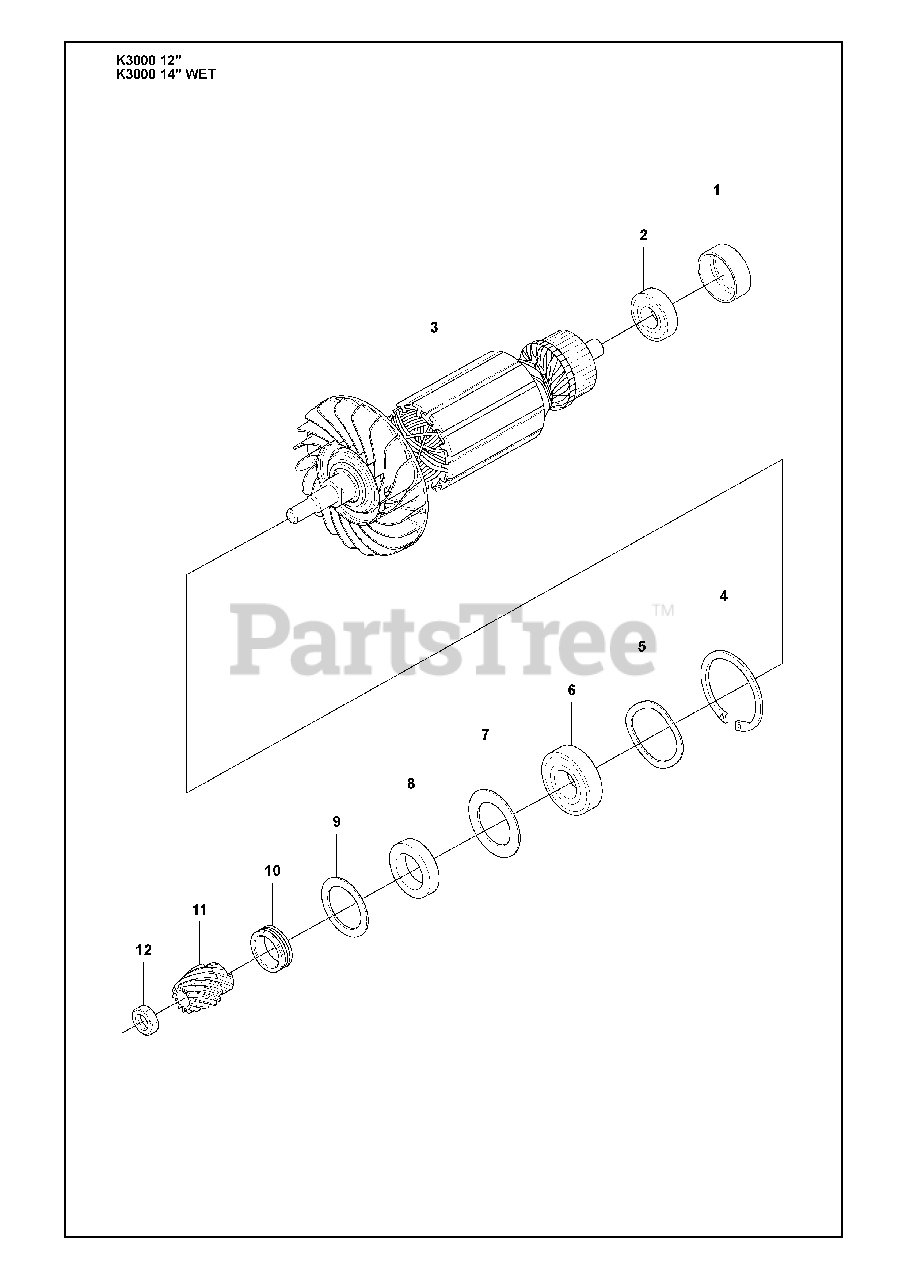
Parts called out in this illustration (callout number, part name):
1	Rubber Bushing
2	Ball Bearing
3	Rotor
5	Spring Washer
6	Ball Bearing
8	Felt Joint
12	Nut
